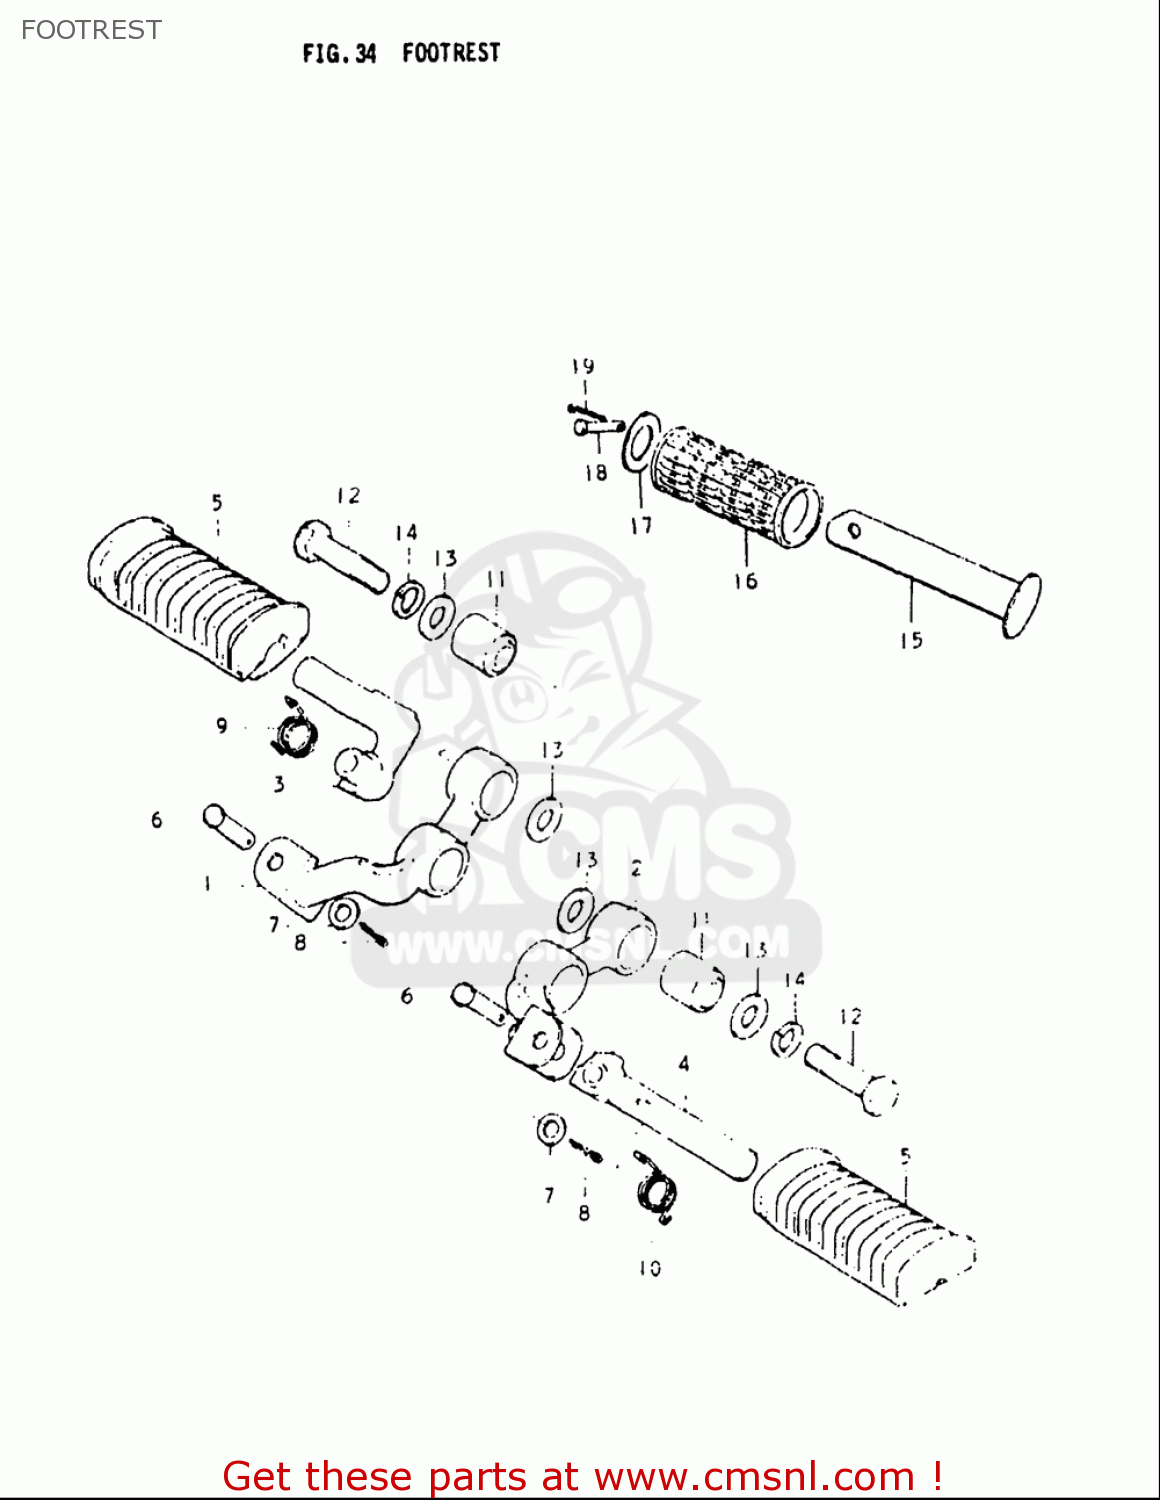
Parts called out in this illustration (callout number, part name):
3	BAR,FRONT FOOTREST,RIGHT NO
5	RUBBER,FR FOOTREST
7	WASHER
8	PIN
9	SPRING
10	SPRING
11	BUSH
12	BOLT(10X38)
13	WASHER(10.5X20X2.3)
14	WASHER,LOCK
15	BAR,FOOTREST RUBBER
16	RUBBER,PILLION FOOTREST
17	WASHER(19.5X32X2)
18	PIN
19	PIN
